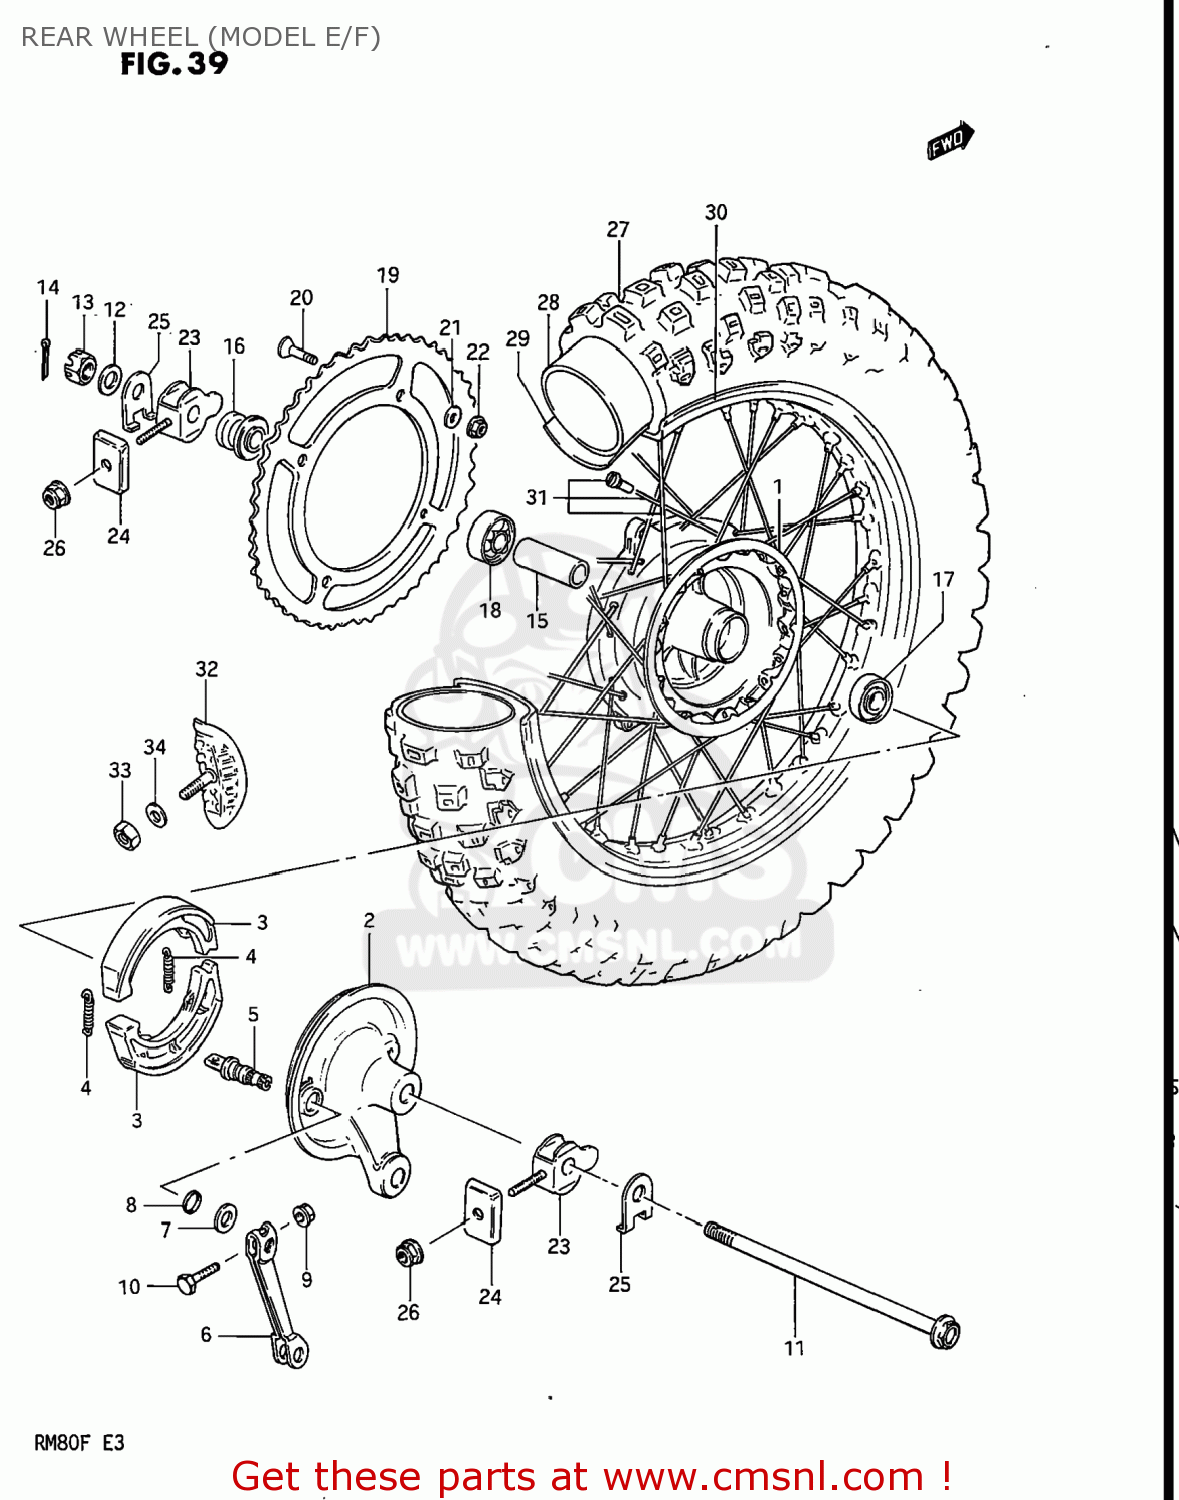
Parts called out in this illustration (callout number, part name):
1	HUB,REAR
2	PANEL,REAR HUB
3	SHOE,BRAKE
4	SPRING(L:35.8)
5	CAM,BRAKE
6	LEVER,RR BRAKE CAM
7	WASHER(12.5X20X1)
8	O RING(D:2.5,ID:11.4)
9	NUT
10	BOLT
11	AXLE,REAR
12	WASHER
13	NUT
14	COTTER PIN
15	SPACER(15.3X21.7X77)
16	SPACER,L
17	BEARING
18	BEARING
19	SPROCKET,REAR
20	SCREW(8X33.5)
21	WASHER
22	NUT
23	ADJUSTER,CHAIN
24	ADJUSTER,CHAIN
25	WASHER
26	NUT
27	TIRE
28	TUBE ASSEMBLY,WHEEL,INNER
29	PROTECTOR,INNER TUBE
30	RIM,REAR WHEEL
31	SPOKE SET
32	STOPPER,BEAD
33	NUT
34	WASHER
